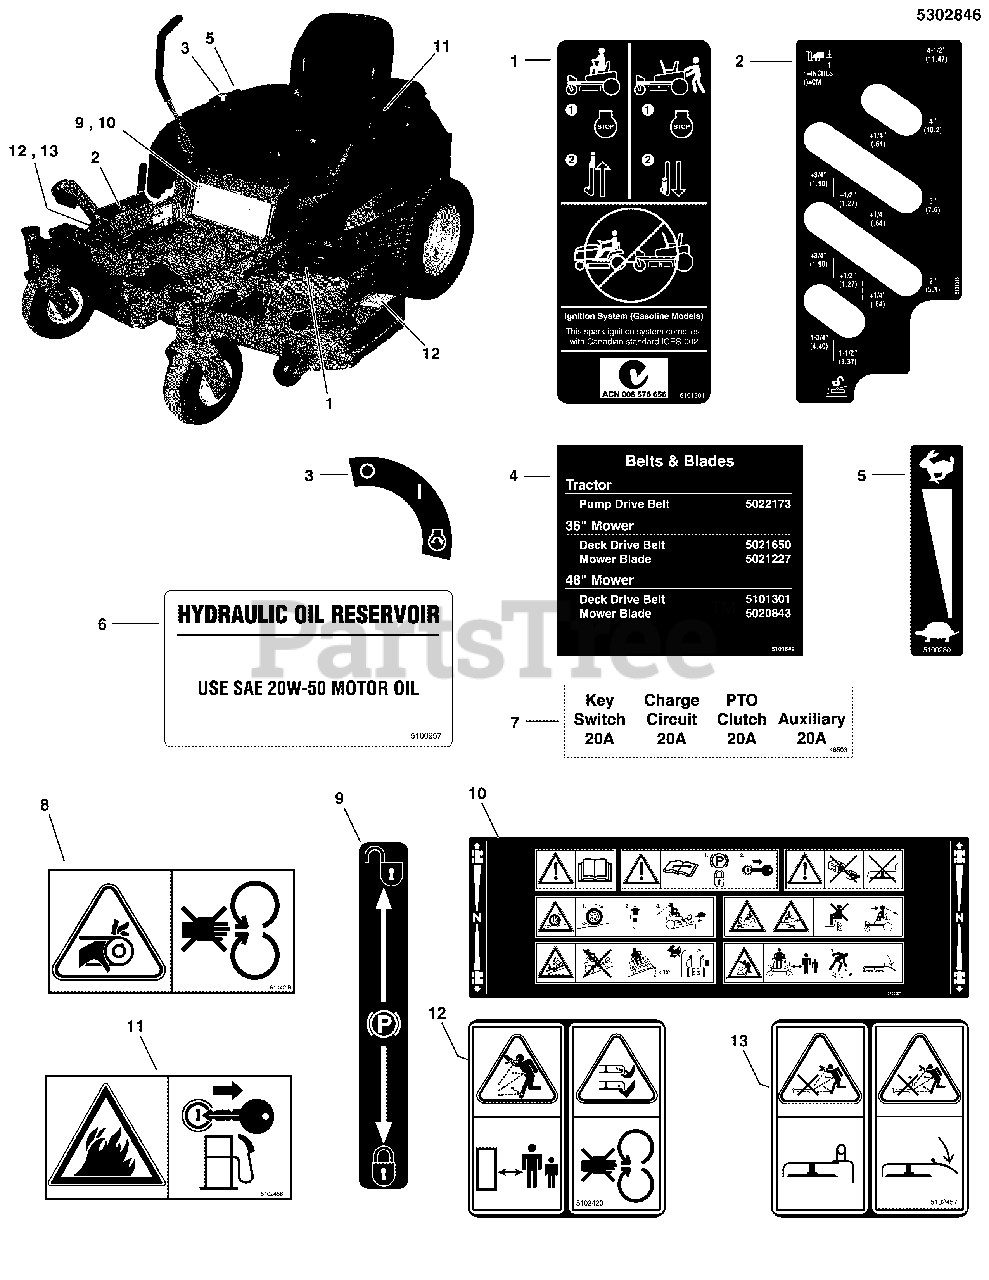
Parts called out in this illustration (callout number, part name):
1	DECAL, TRANSAXLE RELEASE
2	DECAL, CUT HEIGHT, S50X
3	DECAL, IGNITION SWITCH
4	DECAL, BELT & BLADE, S50X iCD
5	DECAL, THROTTLE CONTROL
6	DECAL, HYDRAULIC OIL, SAE 20W50
7	DECAL, FUSE LOCATION
8	DECAL, CE DANGER
9	DECAL, PARKING BRAKE SYMBOLS
10	DECAL, MAIN SAFETY, ANSI CE
11	DECAL, FIRE ANSI EXPORT
12	DECAL, DANGER, MOWER DECK, ANSI EXP
13	DECAL, DANGER DISCHARGE ANSI EXPORT
